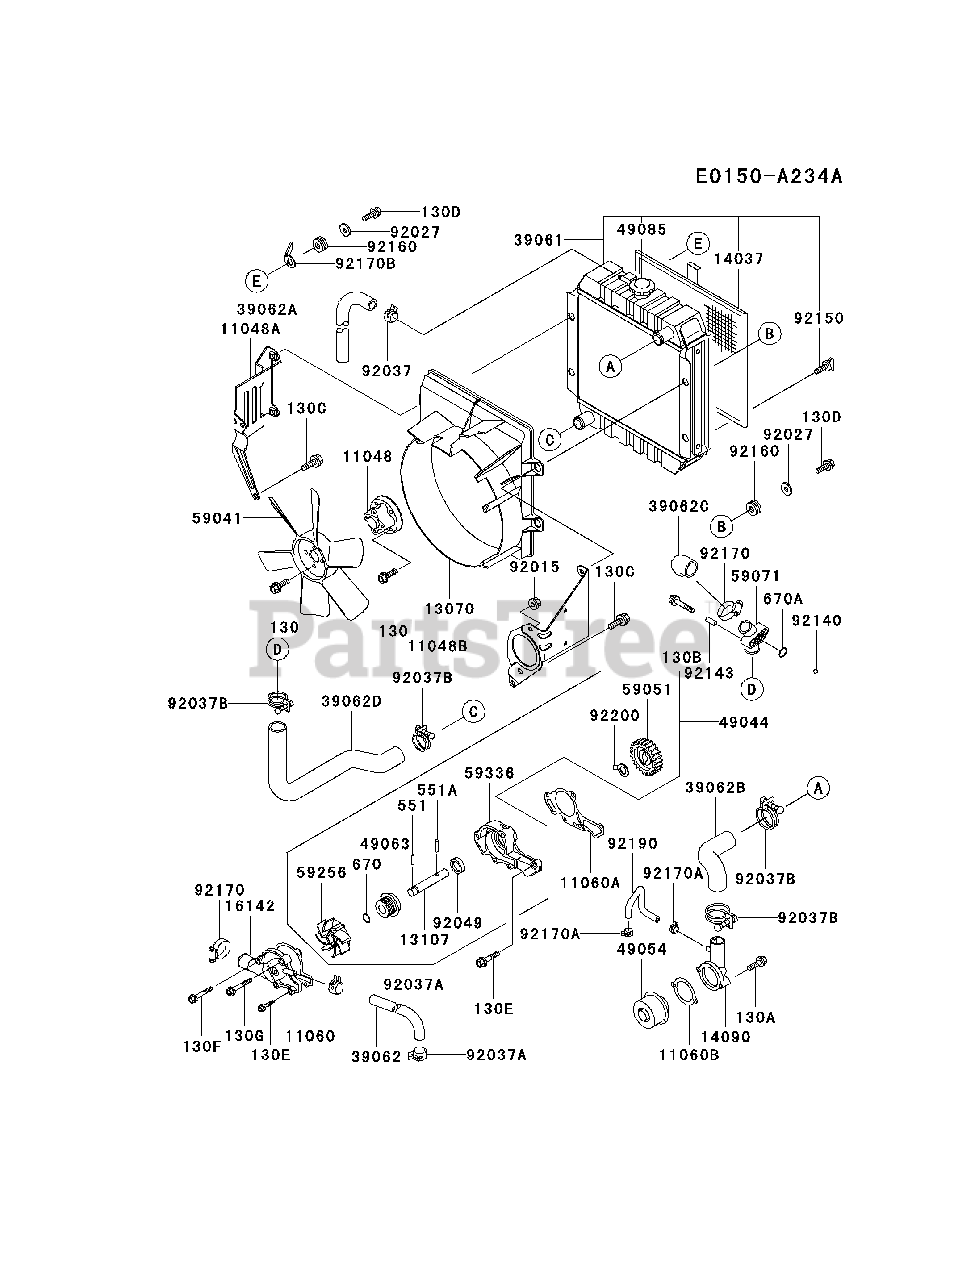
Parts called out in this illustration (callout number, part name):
130	BOLT-FLANGED
130A	BOLT-FLANGED
130B	BOLT-FLANGED
130C	BOLT-FLANGED
130D	BOLT-FLANGED
130E	BOLT-FLANGED
130F	BOLT-FLANGED
130G	BOLT-FLANGED
551	PIN-DOWEL
551A	PIN-DOWEL
670	O RING
670A	O RING
